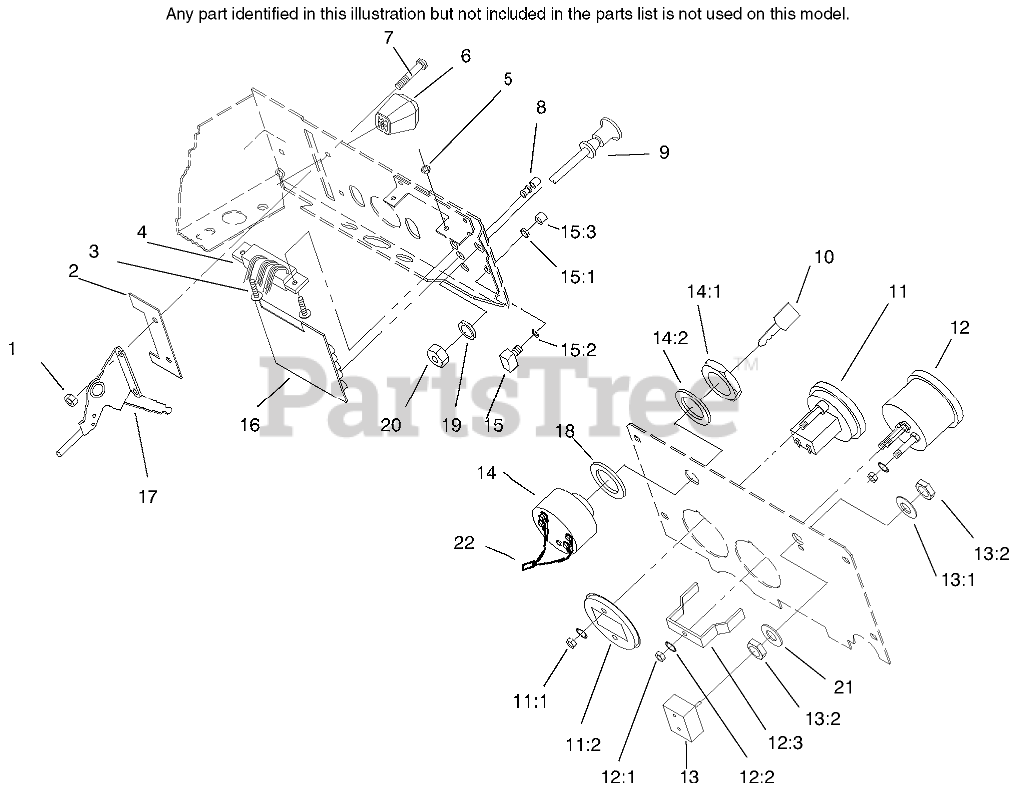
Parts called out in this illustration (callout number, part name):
1	Nut
2	STOP-THROTTLE
7	SCRW-PHC
9	CONTROL CHOKE
10	KEY-IGNITION
11	Hourmeter
11:1	NUT-HEX, KEPS
11:2	Retainer
13	SWITCH-LIGHTS
13:1	TAB-WASHER
14	KEY SWITCH ASM
14:2	Washer-Lock
17	CONTROL-THROTTLE
18	WASHER
19	WASHER-FLAT
20	NUT-HEX PALNUT
21	WASHER
